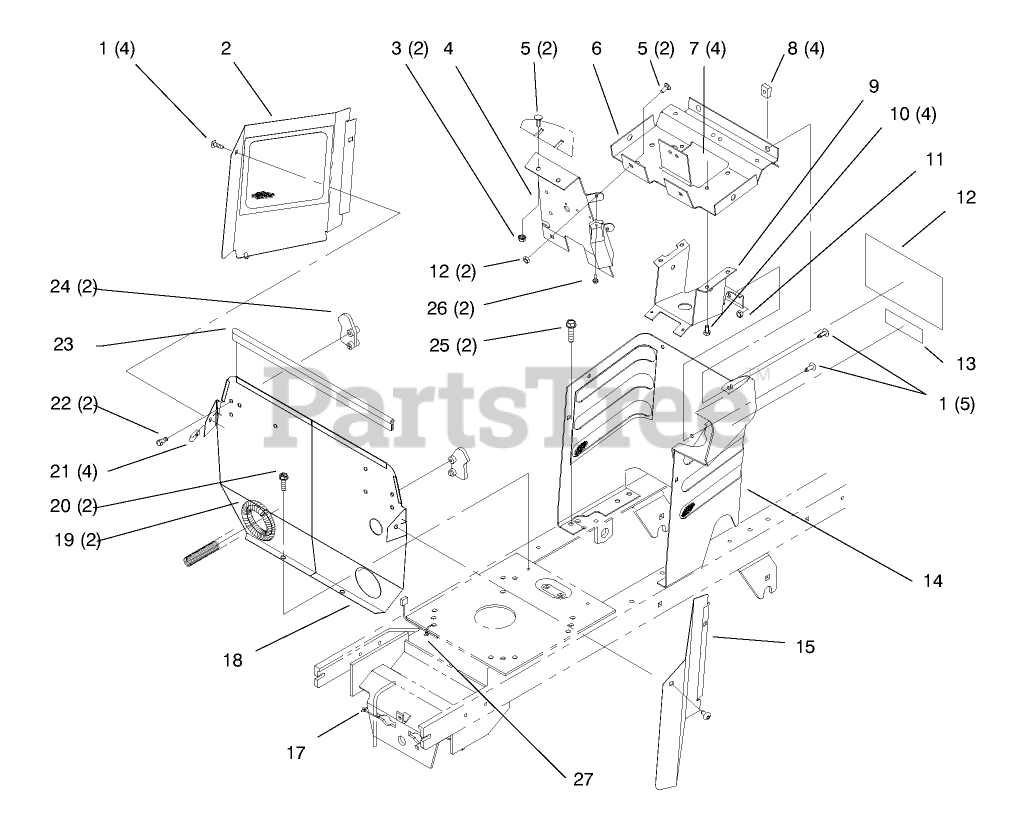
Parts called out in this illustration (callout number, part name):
1	SCREW-HH
2	RH SIDE COVER ASM
3	NUT-KEPS
4	SUPPORT - DASH
5	SCREW-CARR
6	SUPPORT-DASH
7	NUT-HEX
8	NUT RETAINER - J TYPE
9	BRACKET-COLUMN, LOWER
10	SCREW-HH
11	NUT-LOCK, NI
12	DECAL - DANGER
13	DECAL-INSTRUCTION
15	LH COVER ASM
18	FIREWALL
19	COVER-SHAFT, DRIVE
20	SCREW-HWH
22	SCREW-PLASTITE
23	TRIM-SEAL, FIREWALL
24	LATCH-HOOD
25	SCREW-HWHTF
26	SCREW-PPHTF
